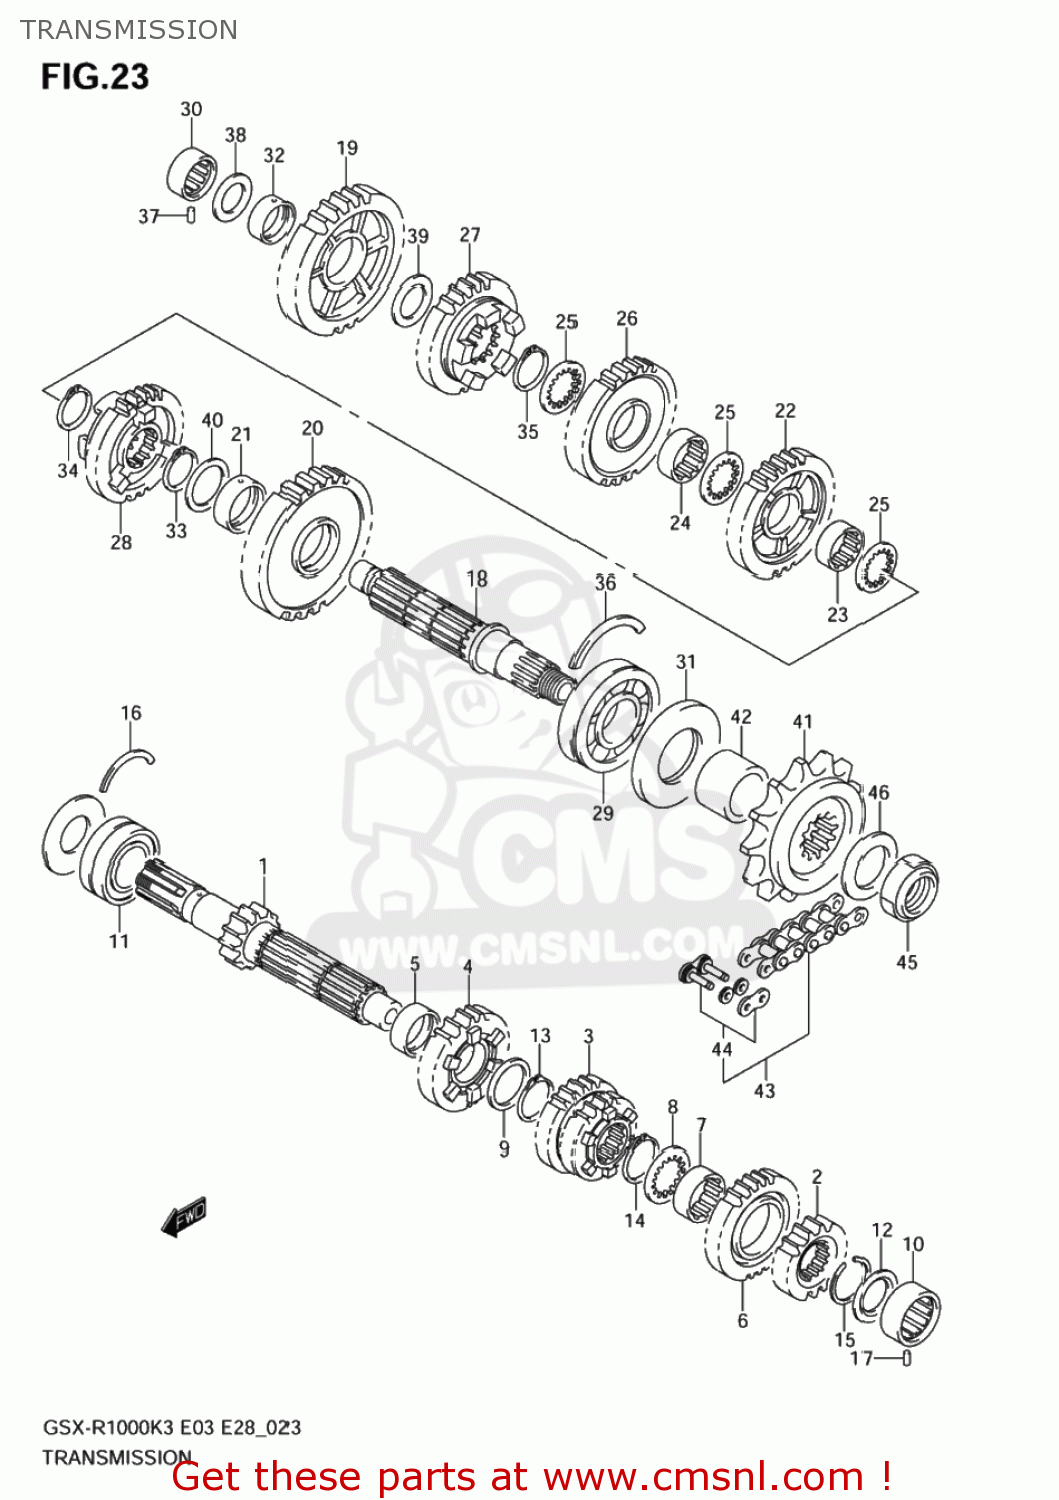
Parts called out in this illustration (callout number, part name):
1	SHAFT,COUNTER
2	GEAR,2ND DRIVE
3	GEAR,3RD & 4TH DRIVE
4	GEAR,5TH DRIVE
5	BUSH,5TH DRIVE GEAR
6	GEAR,6TH DRIVE
7	BUSH,6TH DRIVE GEAR
8	WASHER,LOCK
9	SHIM(27X36X2.5)
10	BEARING(20X34X13.5)
11	BEARING(25X52X20.6)
12	SEAL,OIL(20X31.2X2.7)
13	CIRCLIP
14	CIRCLIP
15	CIRCLIP
16	C RING
17	PIN(6X10)
18	SHAFT,DRIVE
19	GEAR,1ST DRIVEN
20	GEAR,2ND DRIVEN
21	BUSH,2ND DRIVEN GEAR
22	GEAR,3RD DRIVEN
23	BUSH
24	BUSH
25	WASHER,3RD & 4TH DRIVEN
26	GEAR,4TH DRIVEN
27	GEAR,5TH DRIVEN
28	GEAR,6TH DRIVEN
29	BEARING(28X70X18)
30	BEARING(20X34X13.5)
31	SEAL,OIL(34.8X70X6)
32	BUSH
33	CIRCLIP
34	CIRCLIP
35	CIRCLIP
36	C RING
37	PIN(6X10)
38	SHIM(20X34X1)
39	SHIM(22X34X1)
40	WASHER(27X36X1)
41	SPROCKET,ENGINE(NT:17)
42	SPACER,ENG SPROCKET
43	CHAIN ASSY,DRI
44	JOINT SET,ONE SIDE GOLD
45	NUT
46	WASHER(25X40X1.4)
